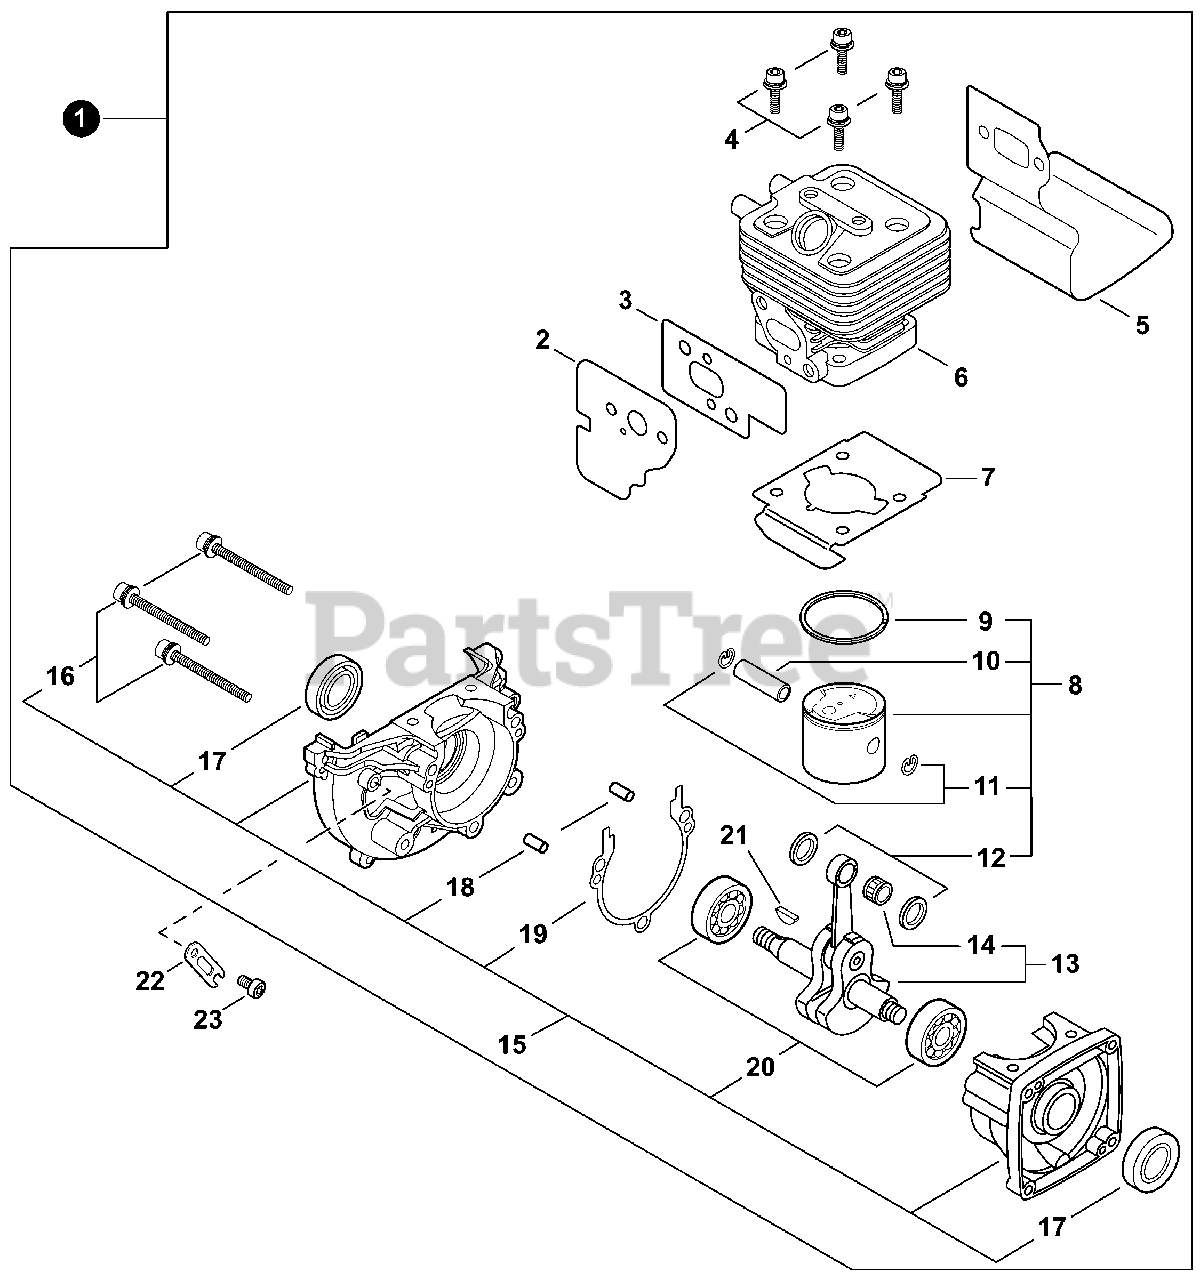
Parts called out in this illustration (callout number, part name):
1	SHORT BLOCK
2	GASKET, INTAKE
3	GASKET, INTAKE
4	BOLT 5×25
5	HEAT SHIELD, EXHAUST
6	CYLINDER
7	GASKET, CYLINDER
8	PISTON KIT
9	RING, PISTON
10	PIN, PISTON
11	RING, SNAP
12	WASHER, THRUST
13	CRANKSHAFT ASSY
14	BEARING, NEEDLE 8
15	CRANKCASE KIT
16	BOLT 5×28
17	SEAL, OIL 12
18	PIN, LOCATING 4×8
19	GASKET, CRANKCASE
20	BEARING, BALL - 6201 C3
21	KEY, WOODRUFF
22	PLATE, EYE
23	BOLT, TORX 5×8
